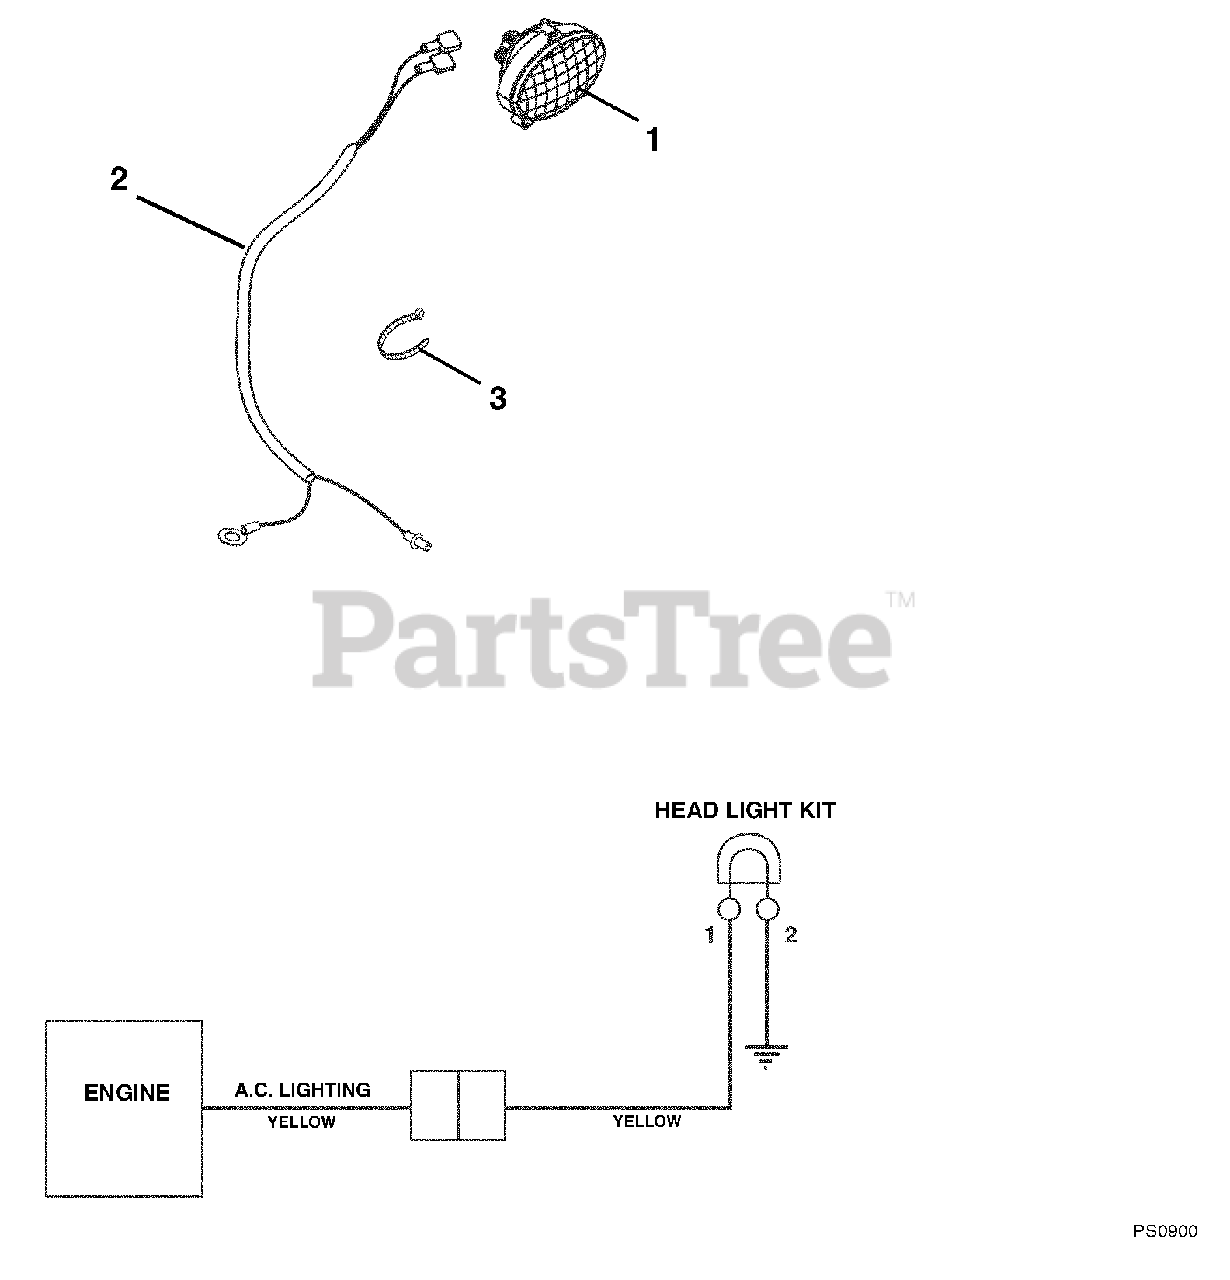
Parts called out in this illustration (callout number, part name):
1	HEADLAMP, OVAL W/ 1156 BULB
2	HARNESS, WIRE-LIGHT
3	CABLE TIE LG 5-1/2
